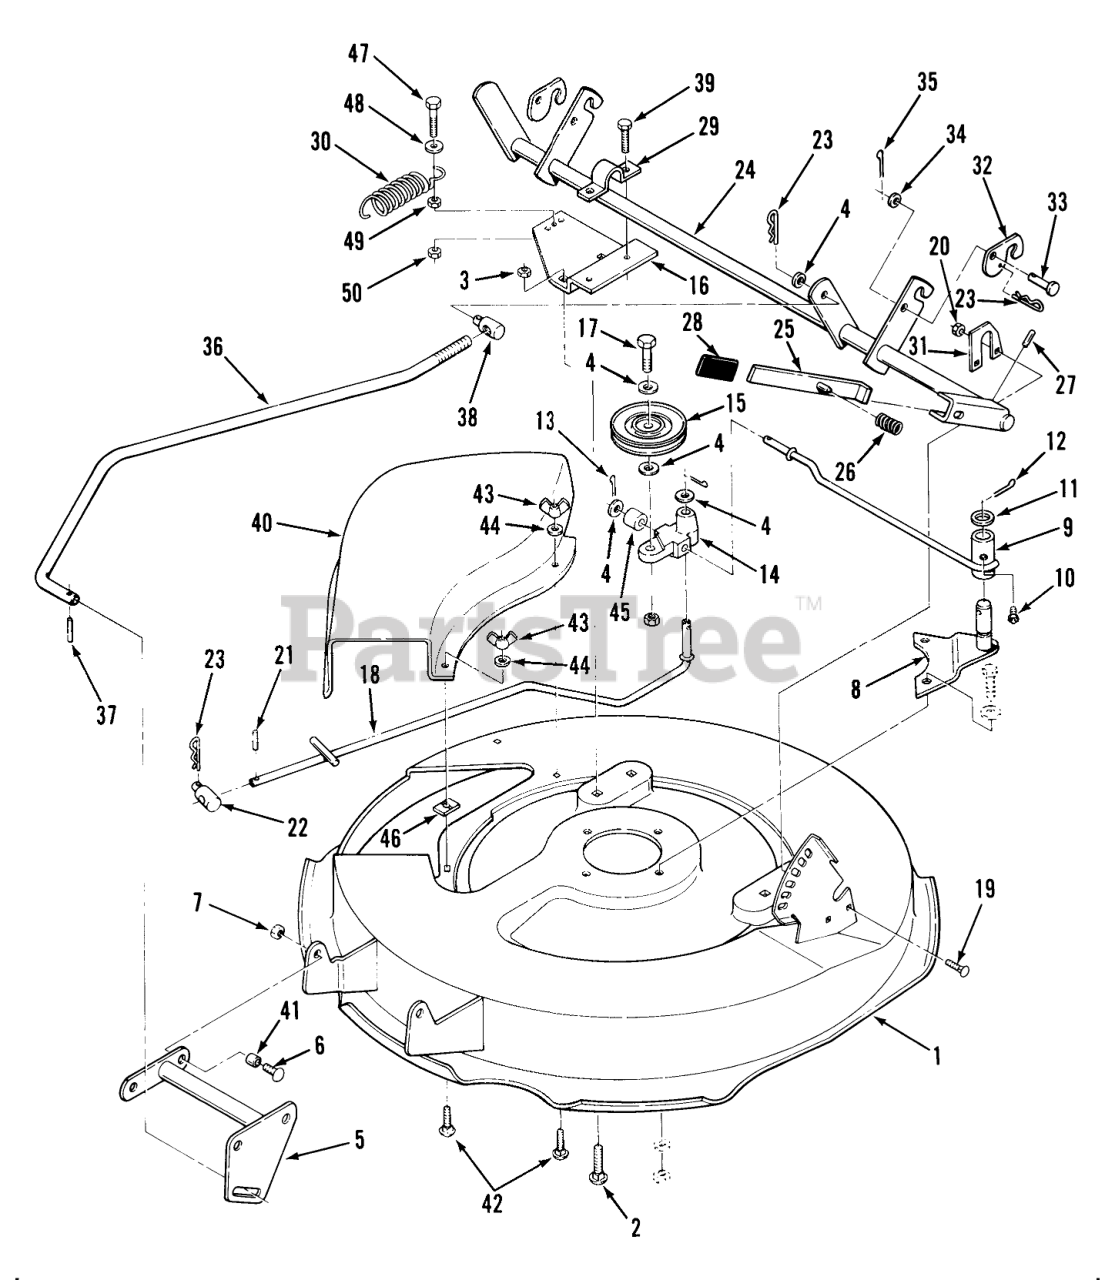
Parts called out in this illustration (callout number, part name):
1	ASM-DECK (30" L) R
1	Spindle Assy (Includes items 3 thru 8)
2	Bolt
3	NUT
4	Washer
5	ASM-FRONT LIFT R
6	Bolt-Carriage
7	LOCKNUT-FLANGE
8	ASM-PIVOT, IDLER
9	WLDMT-IDLER ROD
10	Zerk
11	WASHER
12	Cotter Pin
13	Pop Rivet
14	BLOCK IDLER
15	PULLEY-IDLER V
16	BRACKET-HEIGHT ADJ M R
17	Bolt
18	ASS'Y-IDLER ROD
19	Bolt-Carriage
20	Nut
21	Pin-Roll
22	TRUNNION-LIFT
23	Hairpin Cotter
24	ASSY-HEIGHT ADJ S R
25	LEVER ASSY
26	SPRING-COMPRESSION
27	PIN-SPIROL
30	SPRING-CLUTCH
31	PLATE-RETAINER R
32	Latch
34	Washer
35	Cotter Pin
36	ASS'Y-HEIGHT ADJ R
37	SPIROL PIN
38	STUD-TRUNION
39	Bolt
40	Deflector
41	SPACER
42	Bolt-Carriage
43	Nut-Wing
44	WASHER
45	SPACER
46	SPEED NUT 1/4-20
47	Bolt
48	WASHER 5/16 SAE
49	Nut 5/8-18
50	Nut
